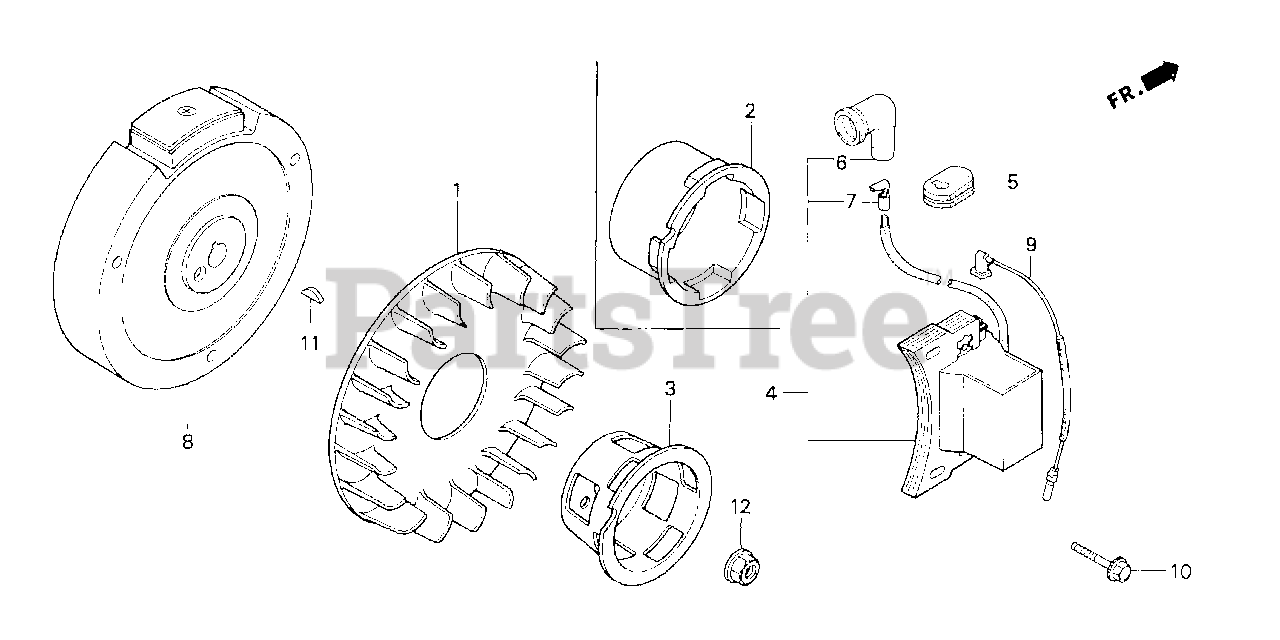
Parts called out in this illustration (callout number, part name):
1	FAN, COOLING
2	PULLEY, STARTER
4	COIL ASSY., IGNITION
5	GROMMET, IGNITION WIRE
6	CAP, IGNITION (TOYO)
7	TERMINAL, PLUG
8	FLYWHEEL
9	WIRE, STOP SWITCH
10	BOLT, FLANGE (6X25)
11	KEY, WOODRUFF (3MM)
12	NUT, FLANGE (12MM)
